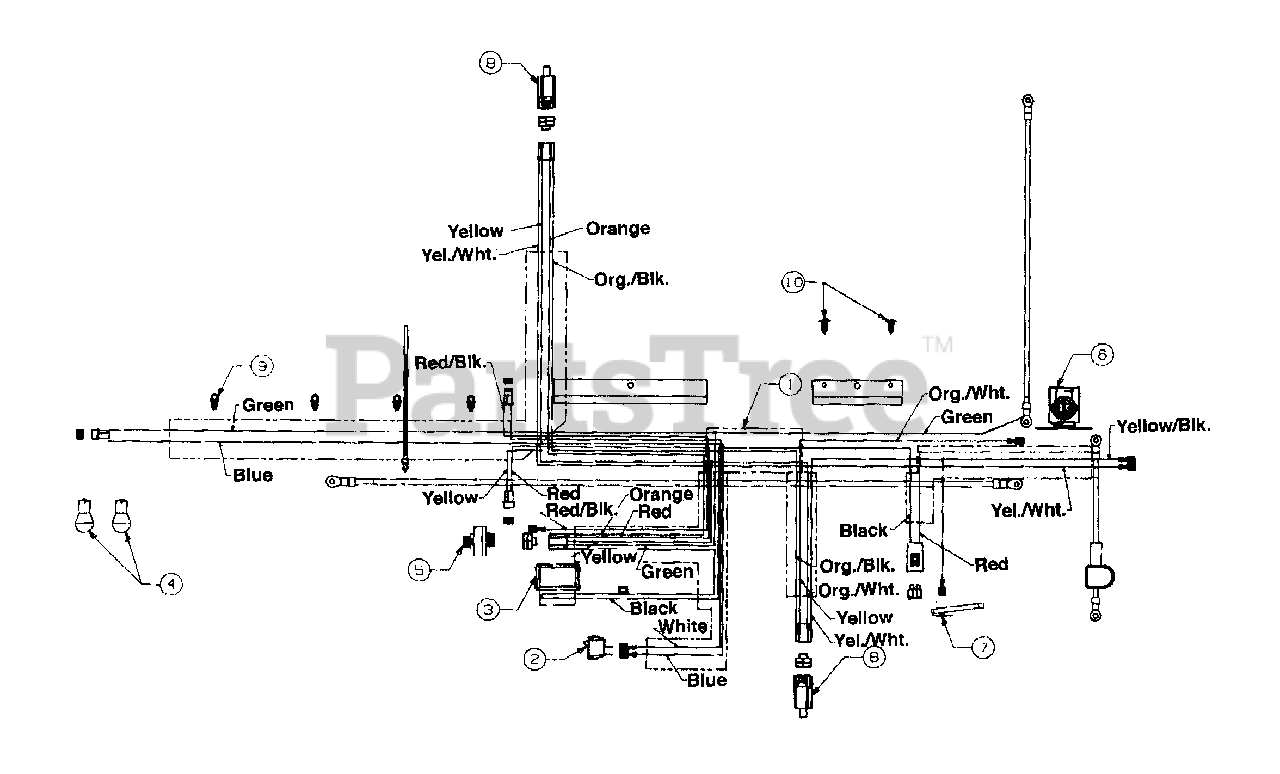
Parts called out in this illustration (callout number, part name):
1	Wire Harness w/Light Switch and Amp
2	Light Switch
3	Ammeter
4	Bulb (Headlight)
5	Ignition Switch
6	Solenoid
7	Safety Switch (Reverse)
8	Safety Switch
9	Wire Retainer Clip
10	Ratchet
